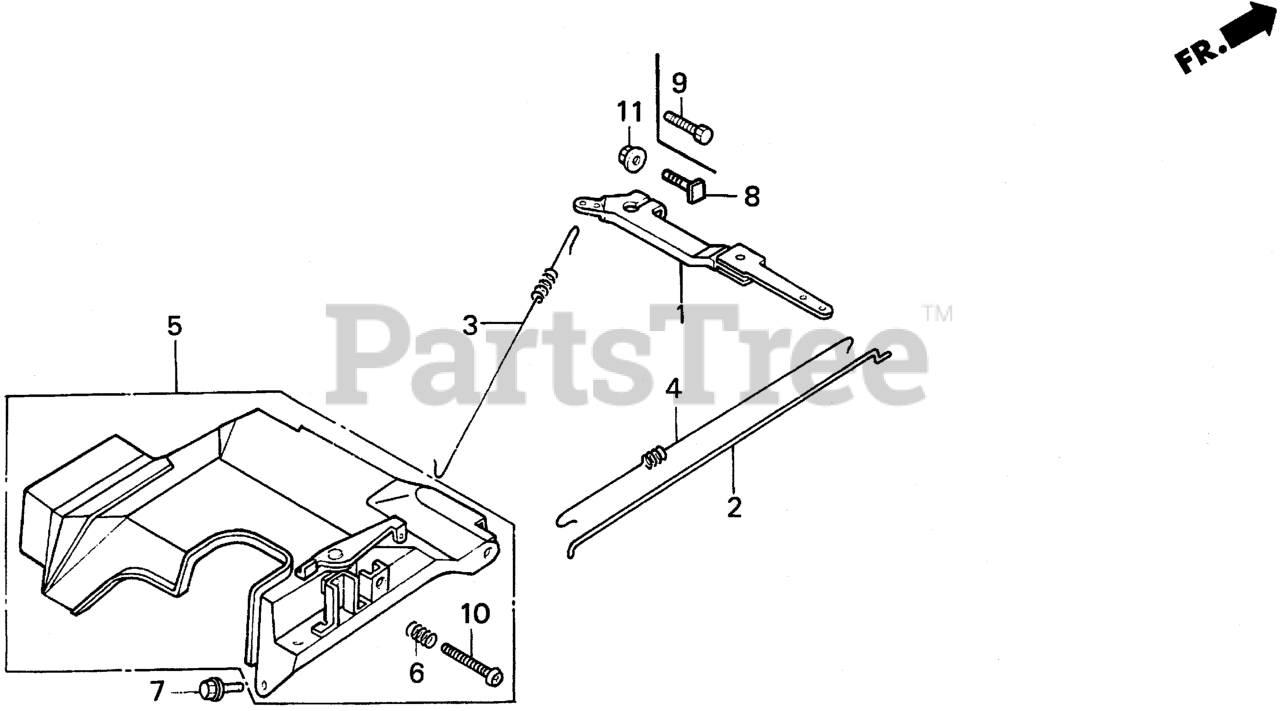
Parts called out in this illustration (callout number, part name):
1	ARM, GOVERNOR
2	ROD, GOVERNOR
3	SPRING, GOVERNOR (L=145.0MM) (WIRE DIAMETER 1.0MM)
4	SPRING, THROTTLE RETURN
5	CONTROL ASSY.
6	SPRING, CONTROL ADJUSTING Use from Engine SN 2327377.
7	BOLT, FLANGE (6X12) (CT200)
8	BOLT, GOVERNOR ARM
9	BOLT, HEX. (6X22)
10	SCREW, PAN (5X35)
11	NUT, FLANGE (6MM)
